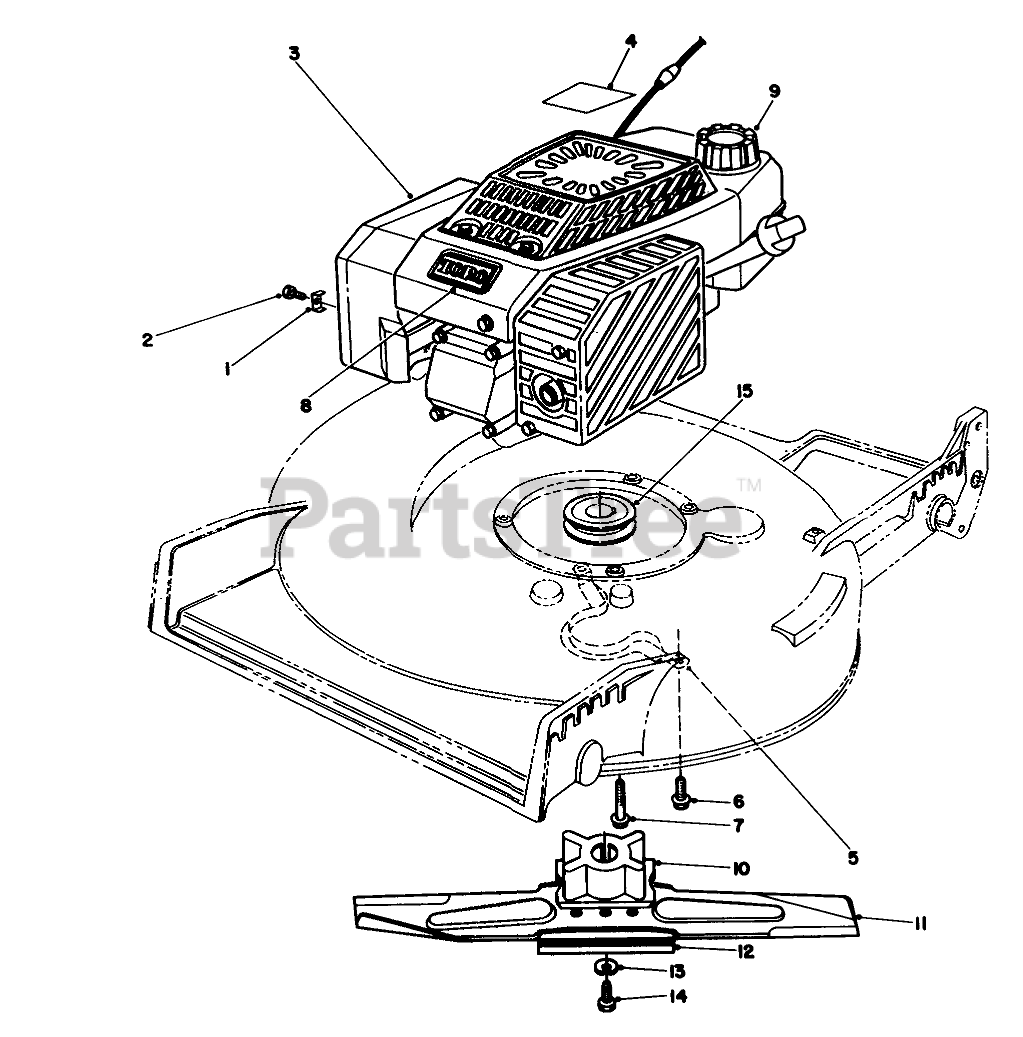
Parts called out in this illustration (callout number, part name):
1	CLAMP-CASING
2	Screw
4	DECAL - ENGINE
5	Guide-Belt
6	SCREW-HWHTF
7	SCREW-HWH
8	TORO LOGO PLATE
9	GAS CAP ASM
10	BLADE RETAINER
11	Blade
12	Stiffener
13	WASHER-LOCK
14	SCREW-BLADE
15	PULLEY-DRIVE, ZONE START
